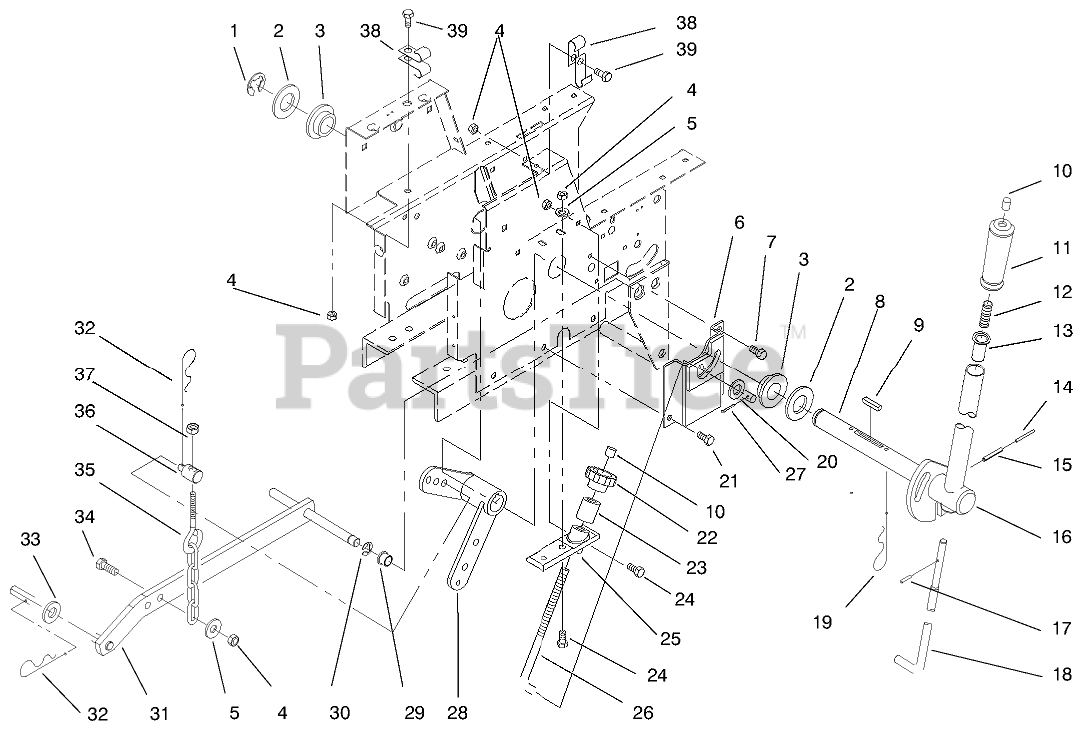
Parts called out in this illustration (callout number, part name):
1	RING-RETAINING
2	WASHER-FLAT
3	BEARING-FLANGE
4	NUT-LOCK, NI
5	WASHER-PLAIN
6	LIFT LEVER ASM
7	Bolt
8	SHAFT-LIFT LEVER
9	KEY-SQUARE
10	CAP-ROD, PLUNGER
11	GRIP-HANDLE
12	SPRING-COMPRESSION
13	RETAINER-SPRING
14	PIN-SPRING
15	PIN-ROLL
16	LIFT HANDLE ASM
17	PIN-SPIROL
18	ROD-LATCH LIFT
19	PIN-HAIR
20	WASHER-FLAT
21	SCREW-SELF TAP
22	KNOB-LIFT CONTROL
23	SLEV-LIFT ADJS
24	SCREW-HH
25	CASTING-LIFT LEVER
26	ROD-HEIGHT CONTROL
27	PIN-COTTER
28	LIFT LEVER ASM
29	BUSHING
30	RING-RETAINING, EXTERNAL
31	Bar-Lift
32	PIN-HAIR
33	WASHER-FLAT
34	SCREW-HH
35	CHAIN-LIFT
36	TRUNNION-LIFT
37	NUT-LOCK, NI
38	CLIP
39	SCREW-HH
